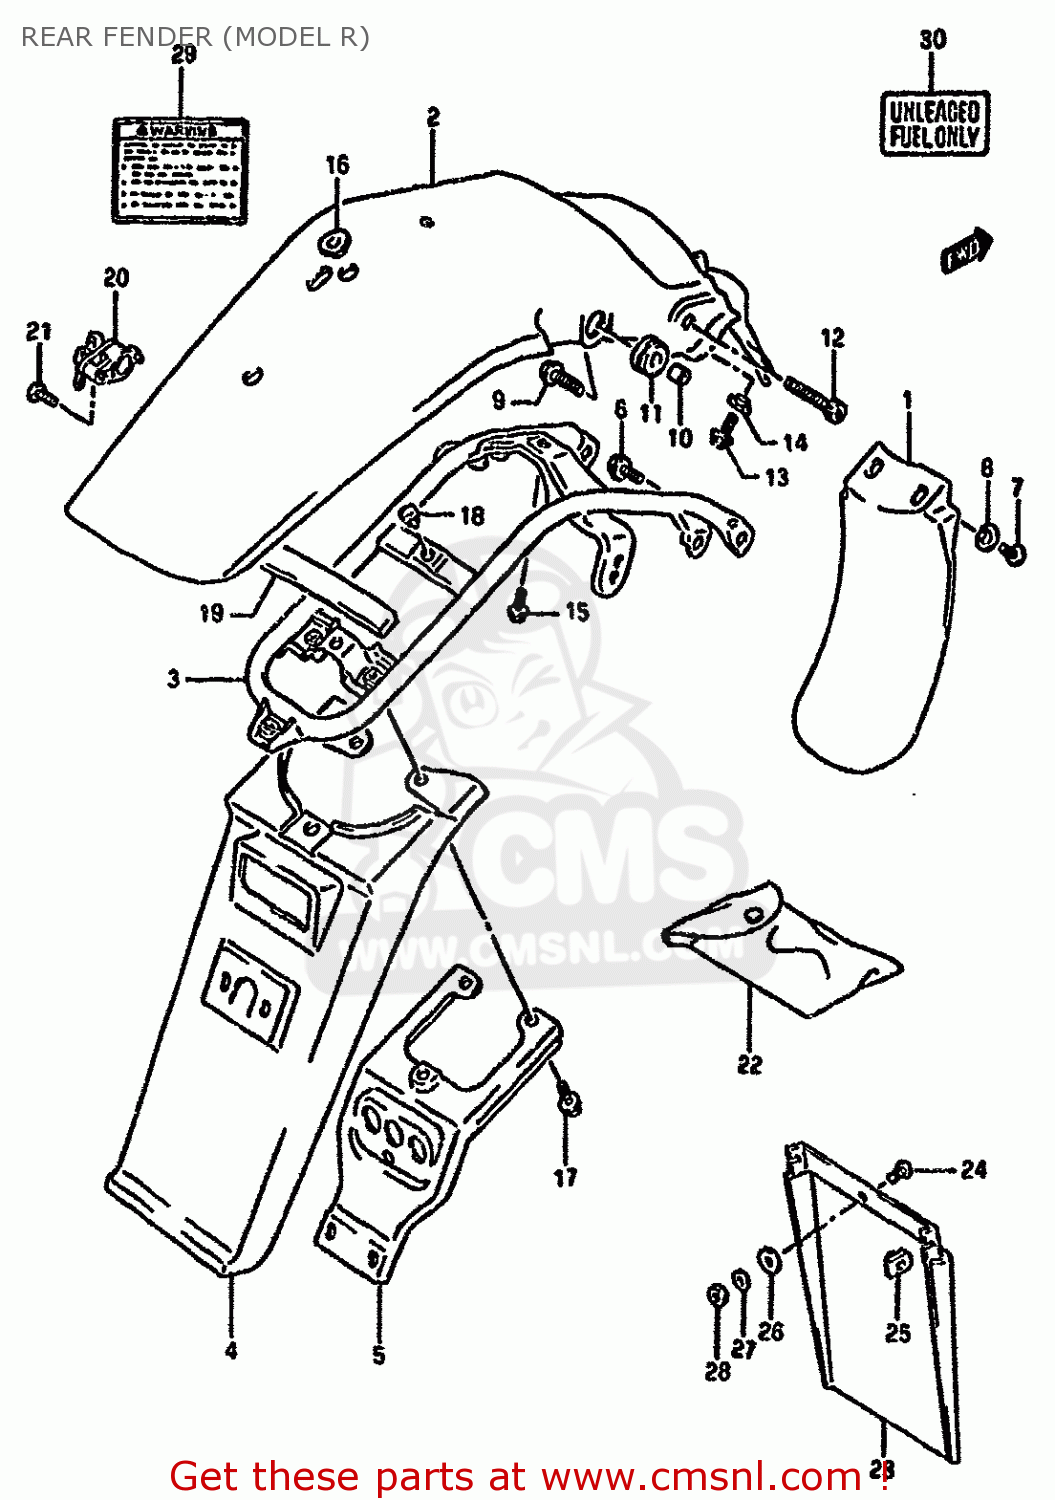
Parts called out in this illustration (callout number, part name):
1	BODY,RR FENDER FR
2	BODY,RR FENDER RR
3	REINF,RR FENDER
4	EXTENSION,RR FENDER
5	REINFORCEMENT,RR FENDER EXT
6	BOLT
7	SCREW 6X12
8	WASHER
9	BOLT(8X30)
10	SPACER (8.8X12X7)
11	CUSHION
12	BOLT(8X30)
13	BOLT
14	WASHER
15	BOLT
16	WASHER(14.2X26X1.2)
17	BOLT
18	CUSHION
19	CUSHION,REAR FENDER
20	LOCK SET,HELMET
21	SCREW
22	TOOL ASSY
23	MUDGUARD,RR FENDER RR
24	SCREW
25	NUT
26	WASHER
27	LOCK,WASHER
28	NUT
29	LABEL, WARNING
30	LABEL,CAUTION
31	LABEL, TIRE AIR PRESSURE
32	MANUAL,OWNER'S
